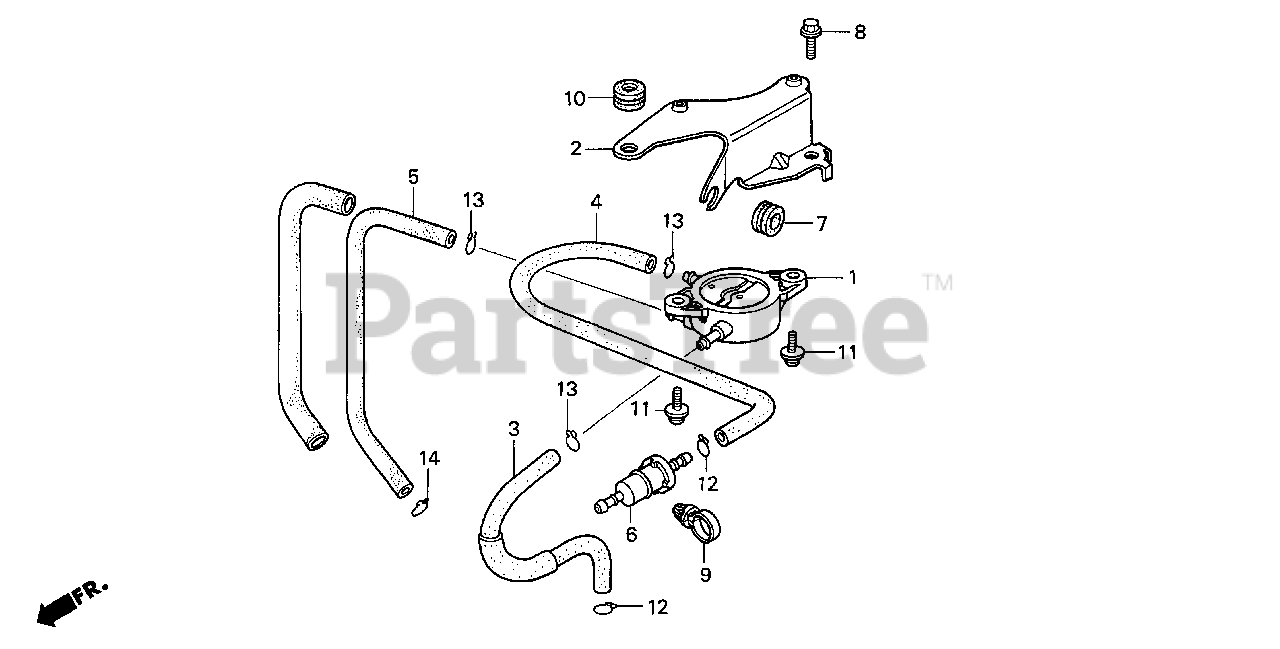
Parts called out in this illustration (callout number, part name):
1	PUMP ASSY., FUEL
2	STAY, FUEL PUMP
3	TUBE A, FUEL
4	TUBE B, FUEL
5	TUBE, DIAPHRAGM
6	FILTER, FUEL
7	GROMMET, RESERVE TANK
8	BOLT, FLANGE (6X14)
9	CLIP, WIRE HARNESS
10	GROMMET, PUMP STAY
11	SCREW-WASHER (6X16)
12	CLIP, TUBE (B8)
13	CLIP, TUBE (B10)
14	CLIP, TUBE (C9)
